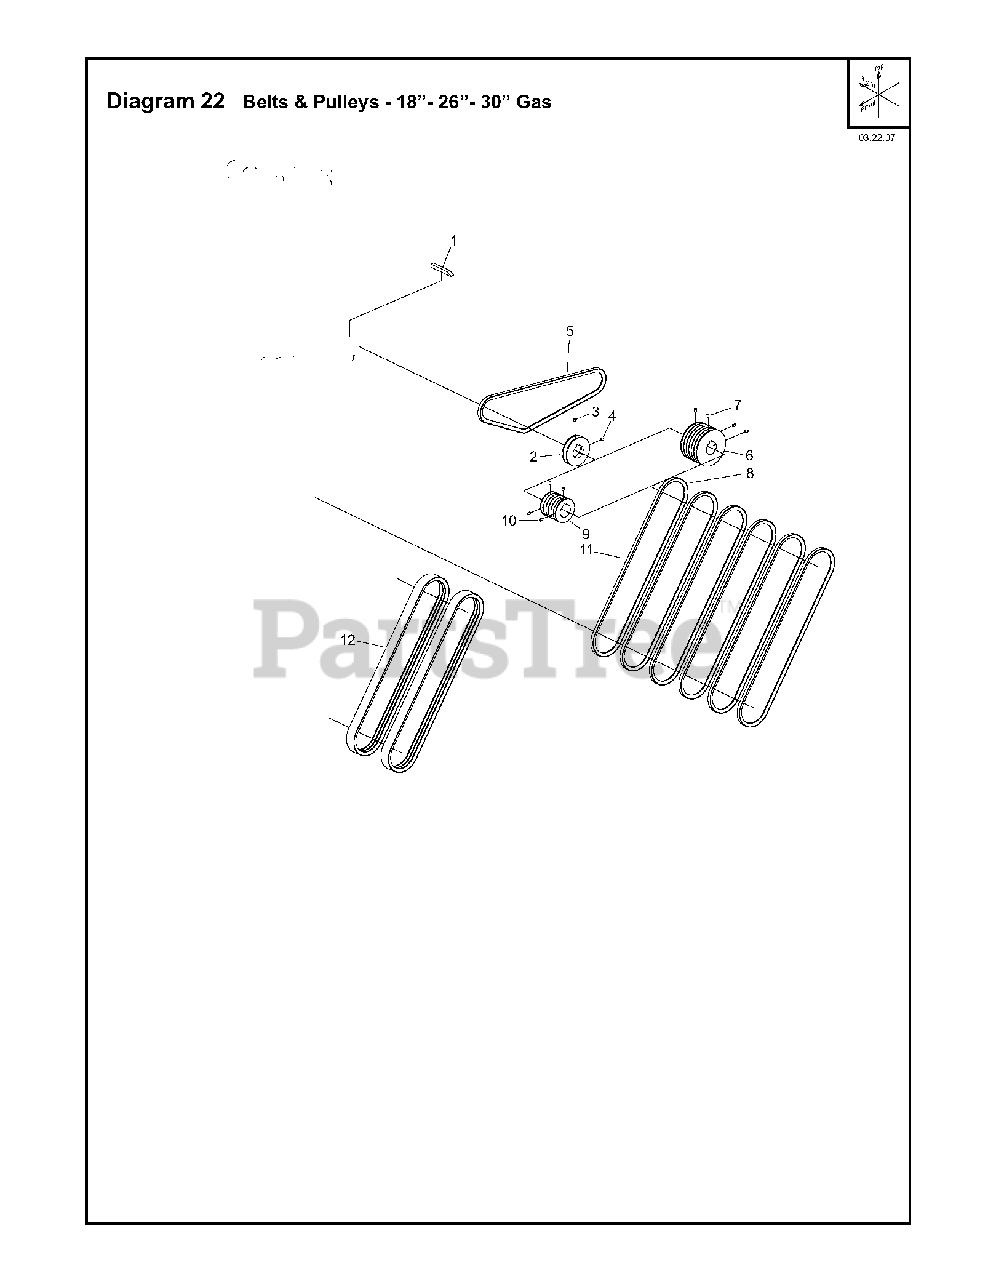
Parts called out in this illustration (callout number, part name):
1	KEY. BEVEL .375 SQ. x 3.25
4	SHSS. .25-20 x .375 CUP HK
5	HANDLE.UPPER.GRIPPED
7	SHSS. .25-20 x .375 CUP HK
8	V-BELT
11	V-BELT
12	V-BELT
